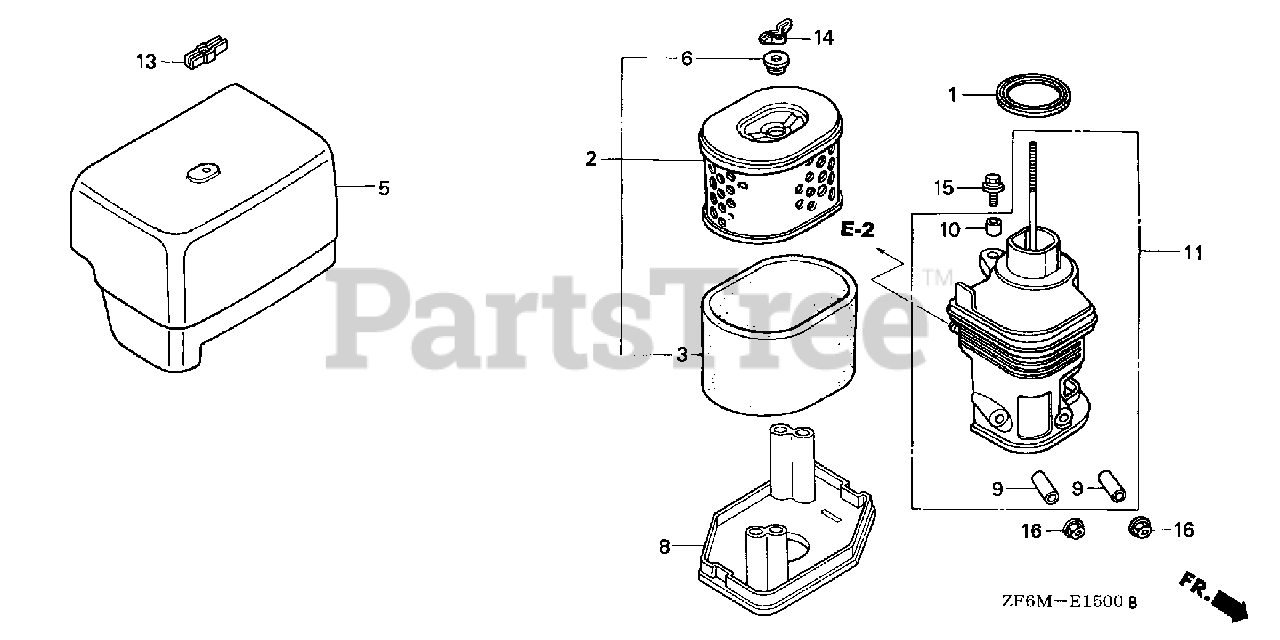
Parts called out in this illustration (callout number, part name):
1	GASKET, ELBOW
2	ELEMENT, AIR CLEANER
3	FILTER (OUTER)
5	COVER, AIR CLEANER
6	GROMMET, AIR CLEANER
8	NOSE, MUFFLER
9	COLLAR, AIR CLEANER
10	COLLAR B, AIR CLEANER
11	ELBOW, AIR CLEANER
14	WINGNUT, TOOL BOX SETTING
15	BOLT-WASHER (6X22)
16	NUT, FLANGE (6MM)
